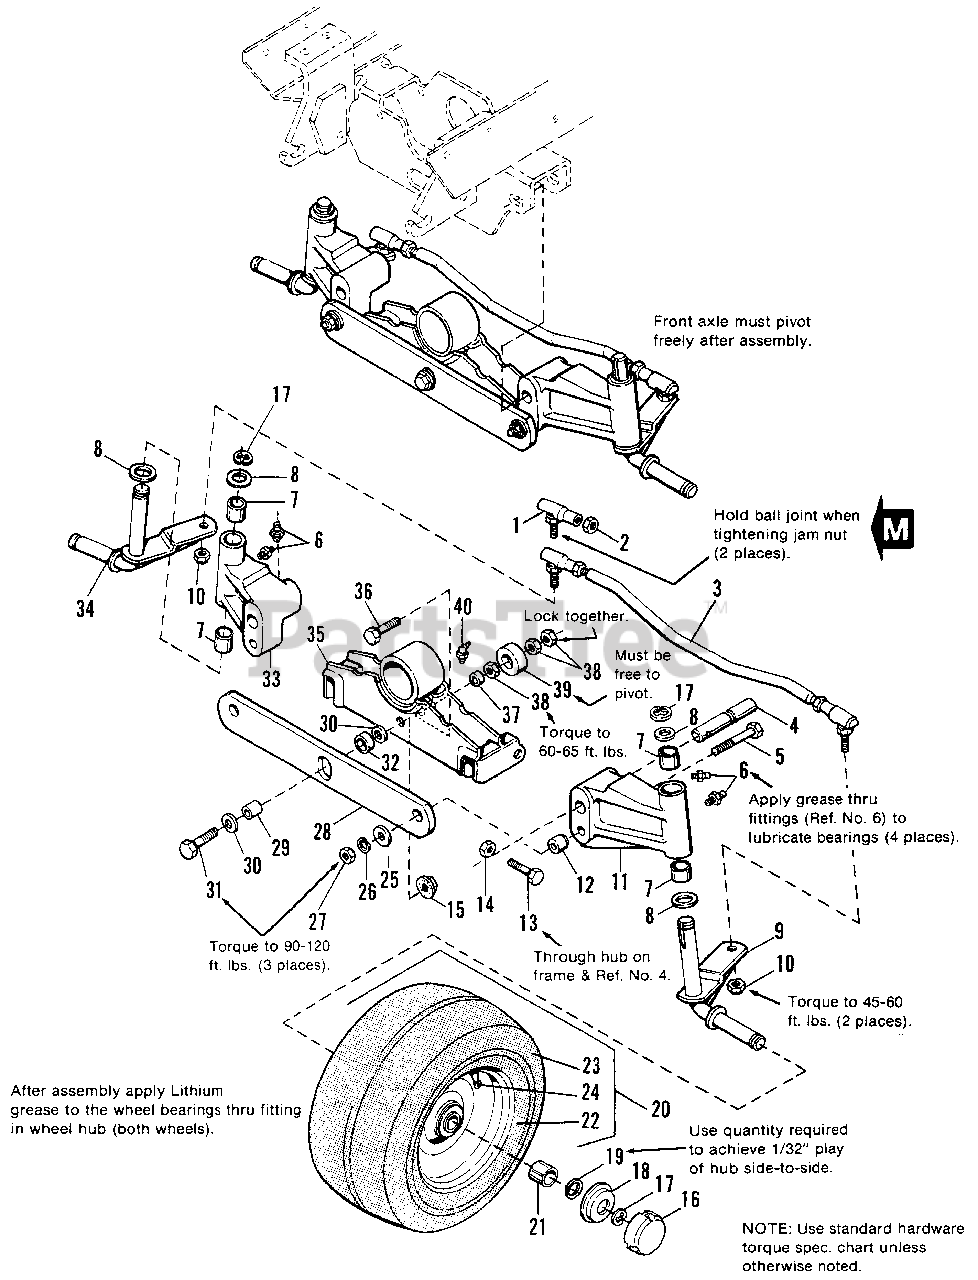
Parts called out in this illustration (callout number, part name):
1	BALL JOINT ASSY.
2	NUT, Hex, Jam, 1/2-20
3	TIE ROD ASSY. (Incl. Ref. No. 1 & 2)
4	PIN, Axle Pivot
5	CAPSCREW, Hex Hd., 1/2-13 x 2-3/4, Gr. 8 (Incl. Ref. No. 27)
6	FITTING, Lube, 1/4-28
7	BUSHING, Spindle
8	WASHER, 1-1/32 x 1-5/8 x 1/16
9	SPINDLE ASSY., L.H.
10	NUT, Hex, Centerlock, 1/2-20
11	AXLE PIVOT ASSY., L.H. (Incl. Ref. Nos. 6 & 7)
12	SPACER, Axle Link
13	CAPSCREW, Hex Hd., 5/16-18 x 1-3/4, Gr. 5
14	NUT, Hex, Centerlock, 5/16-18
15	NUT, Hex, Flange, 1/2-13
17	RING, Retainer
18	RETAINER, Hub Cap
19	WASHER, Shim, 1" I.D. x 1-5/8" O.D. x 1/32" (As Required-Qty.)
20	FRONT WHEEL & TIRE ASSY., 16 x 61/2-8 (Incl. Ref. Nos. 22. 23 & 24)
21	BEARING
22	WHEEL ASSY., w/ Bearings (Incl. Ref. No. 21)
23	TIRE, 16 x 6.50-8
24	VALVE STEM & CAP
25	WASHER, 9/16 I.D. x 1-3/8 O.D. x 7/64
26	WASHER, Lock, 1/2
27	NUT, Hex, 1/2-13
29	SPACER, Front Hitch
30	WASHER, 1/2" I.D. x 1-1/4 O.D. x 3/16
31	CAPSCREW, Hex Hd., 1/2-13 x 2, Gr. 8
32	SPACER, 7/8 I.D. x 1-1/4 O.D. x 21/32
33	AXLE PIVOT ASSY., R.H. (Incl. Ref. Nos. 6 & 7)
34	SPINDLE ASSY., R.H.
35	HITCH SUPPORT ASSY. (Incl. Ref. No. 40)
36	CAPSCREW, Hex Hd., 1/2-13 x 1-3/4, Gr. 8
37	SPACER, Front Axle
38	NUT, Hex, Jam, 1/2-13
39	RETAINER, Front Axle
40	FITTING, Lube, 45, 114 Drive Type
